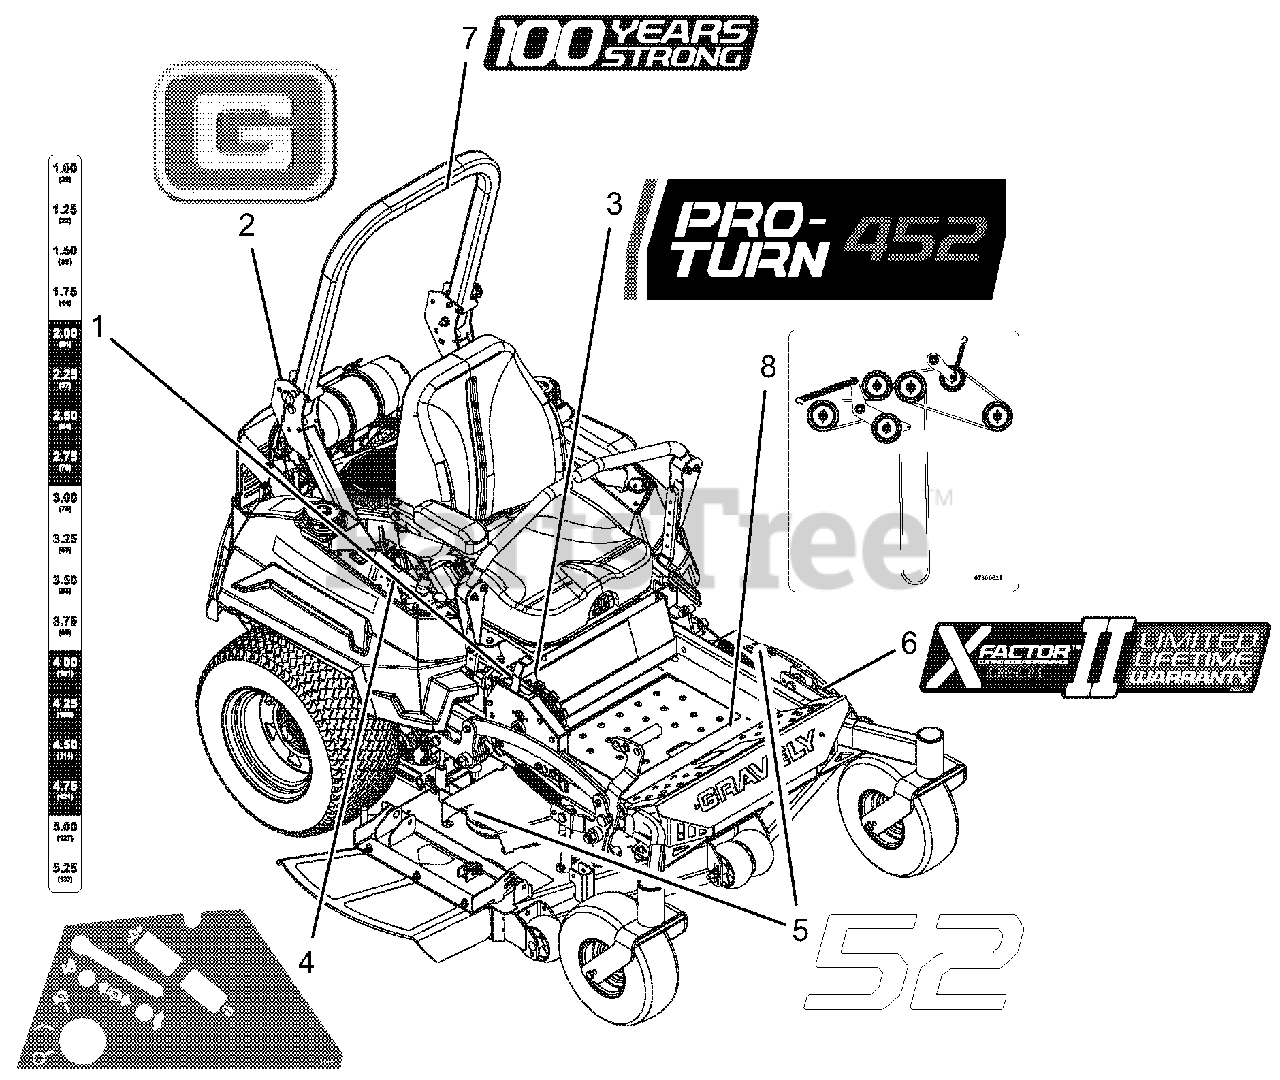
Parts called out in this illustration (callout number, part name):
1	DECAL, PT400 HEIGHT OF CUT
2	DECAL, GRAVELY BRAND
3	DECAL, PRO-TURN 452
4	DECAL, EFI CONTROL PANEL
5	DECAL, 52"
6	DECAL, X-FACTOR DECK
7	DECAL, GRAVELY 100 YEAR
8	DECAL, BELT ROUTE RH V-SIDE IDLER
